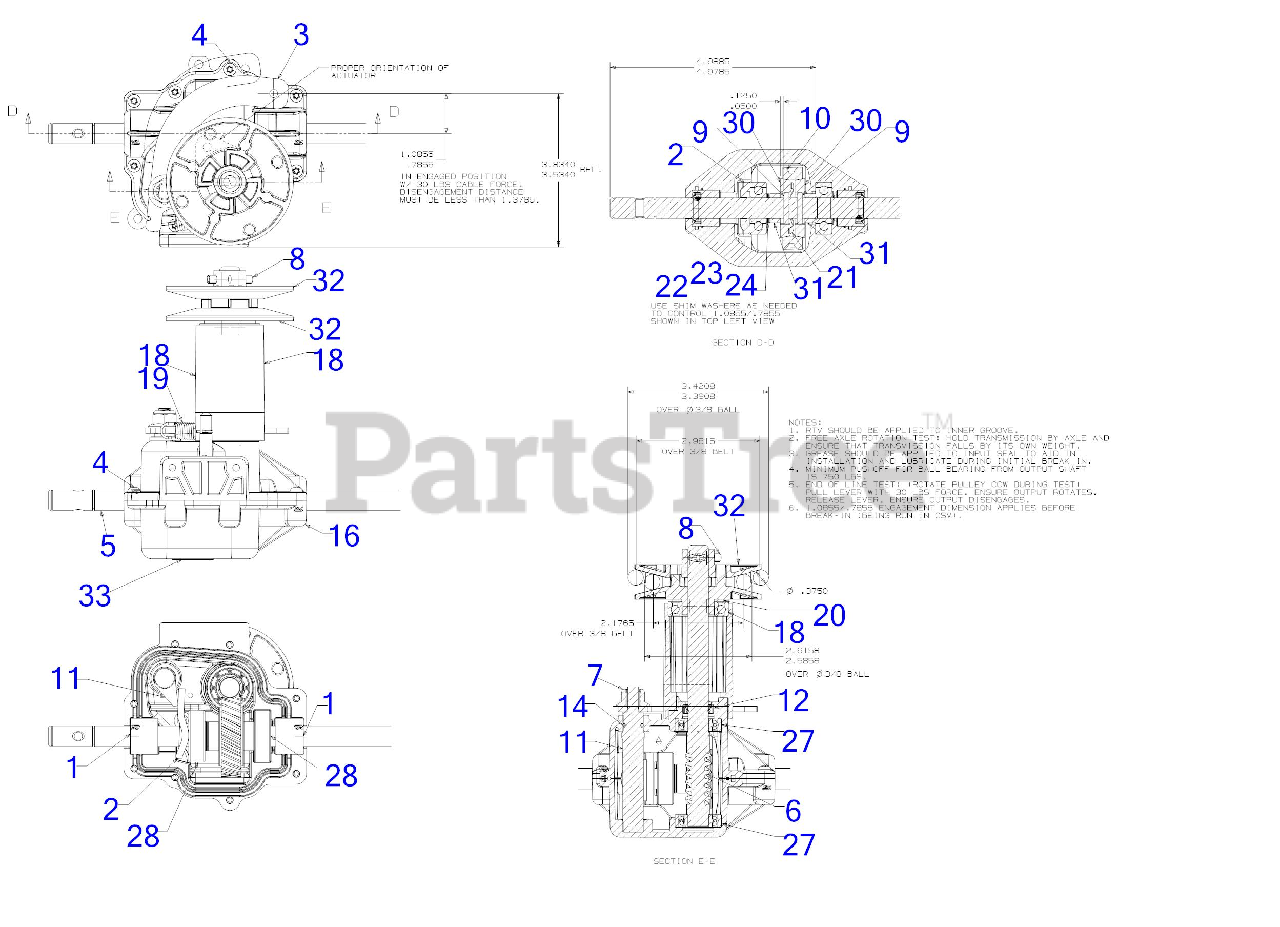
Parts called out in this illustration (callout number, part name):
1	BEARING ASSEMBLY
2	ACTUATOR PLATE
3	CLUTCH LEVER
4	SCREW .159 x .610
5	OUTPUT SHAFT
6	INPUT SHAFT
9	DOWEL PIN
10	28T GEAR
11	ACTUATOR
14	O-RING
16	LOWER HOUSING
18	CAM TUBE
19	EXTENSION SPRING
20	FLAT WASHER .793ID x 1.24OD x .060
21	WASHER
22	FLAT WASHER .504 X.700X.010
23	WASHER
24	FLAT WASHER
27	BALL BEARING
28	BEARING
30	HUB
31	SPACER
32	HALF PULLEY
33	LABEL
